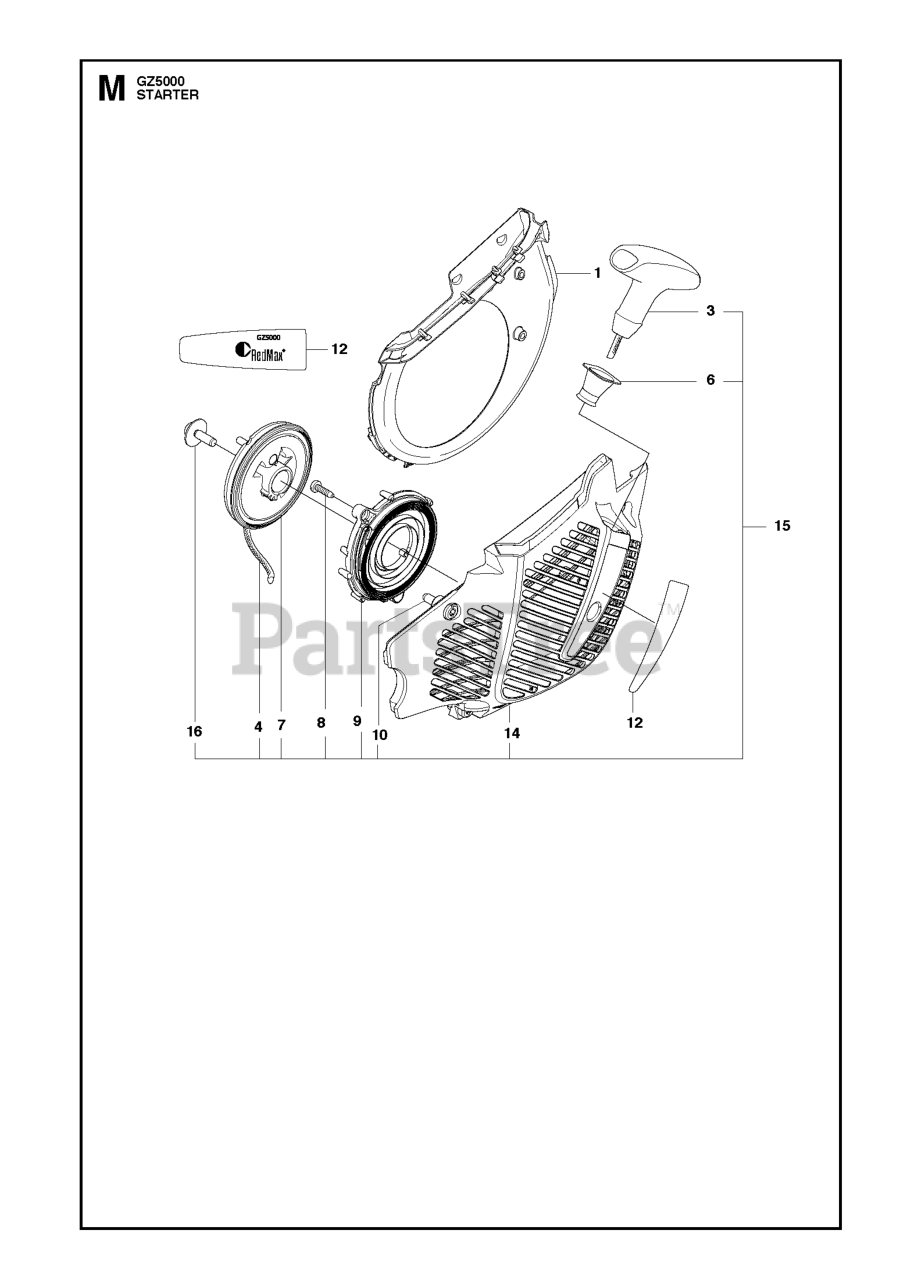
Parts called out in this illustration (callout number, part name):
1	COOLING AIR CONDUCTOR
3	STARTER HANDLE
4	STARTER CORD
7	STARTER PULLEY ASSY
8	SCREW CITXPANT
9	SPRING CASSETTE ADDY
10	SCREW CITXPANMO
12	DECAL 50CC STARTER REDMAX GZ5
14	STARTER HOUSING ASSY JONSERED
15	STARTER ASSY
16	SCREW ITXSCT MT5X16 10.9 TBO
